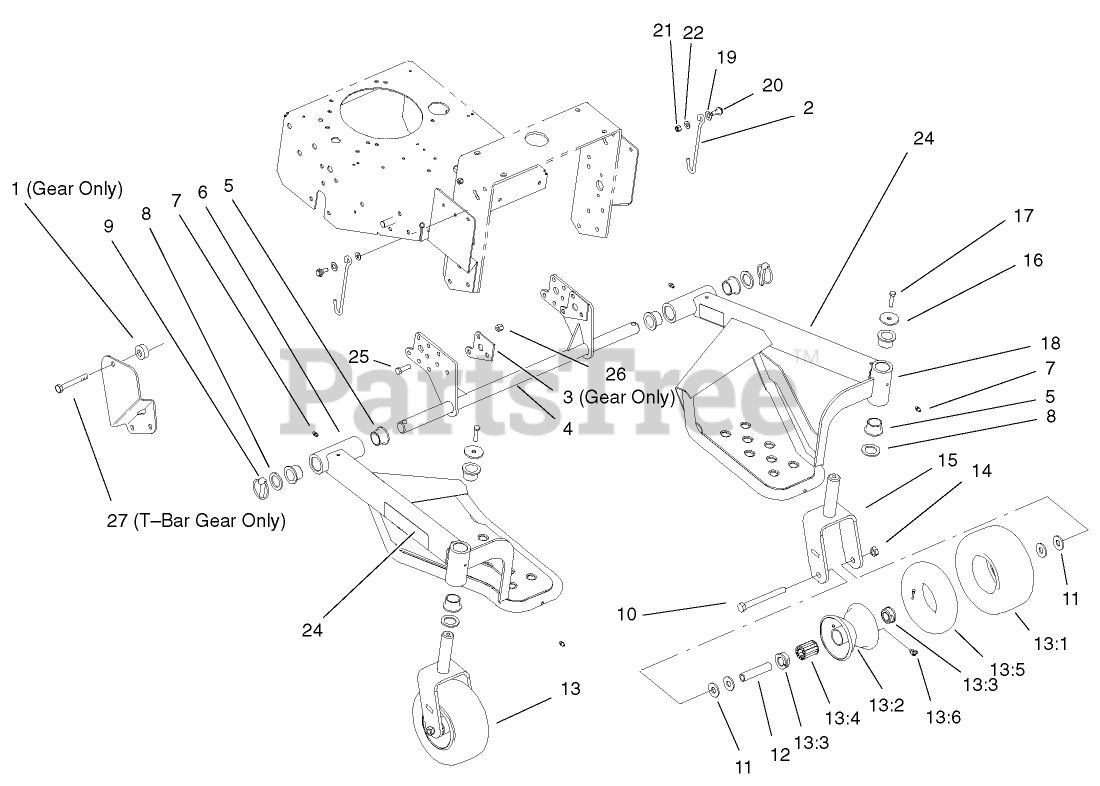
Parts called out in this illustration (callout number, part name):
5	BUSHING
7	FITTING-GREASE
8	WASHER-THRUST
9	PIN-LYNCH
10	SCREW-HH
11	WASHER-FLAT
12	SPANNER-TIRE
13	CASTOR WHEEL ASM
13:2	RIM ASM
13:3	BEARING-OUTSIDE
13:4	BEARING-ROLLER
13:6	FITTING-LUBE, 45 DEG
14	NUT-HEX
16	WASHER-REBOUND
17	SCREW-HH
19	WASHER-BELLEVILLE
20	BOLT-SHOULDER
21	NUT-LOCK, NI
22	WASHER-THRUST
25	SCREW-HH
26	NUT-LOCK, NI
27	SCREW-HH
